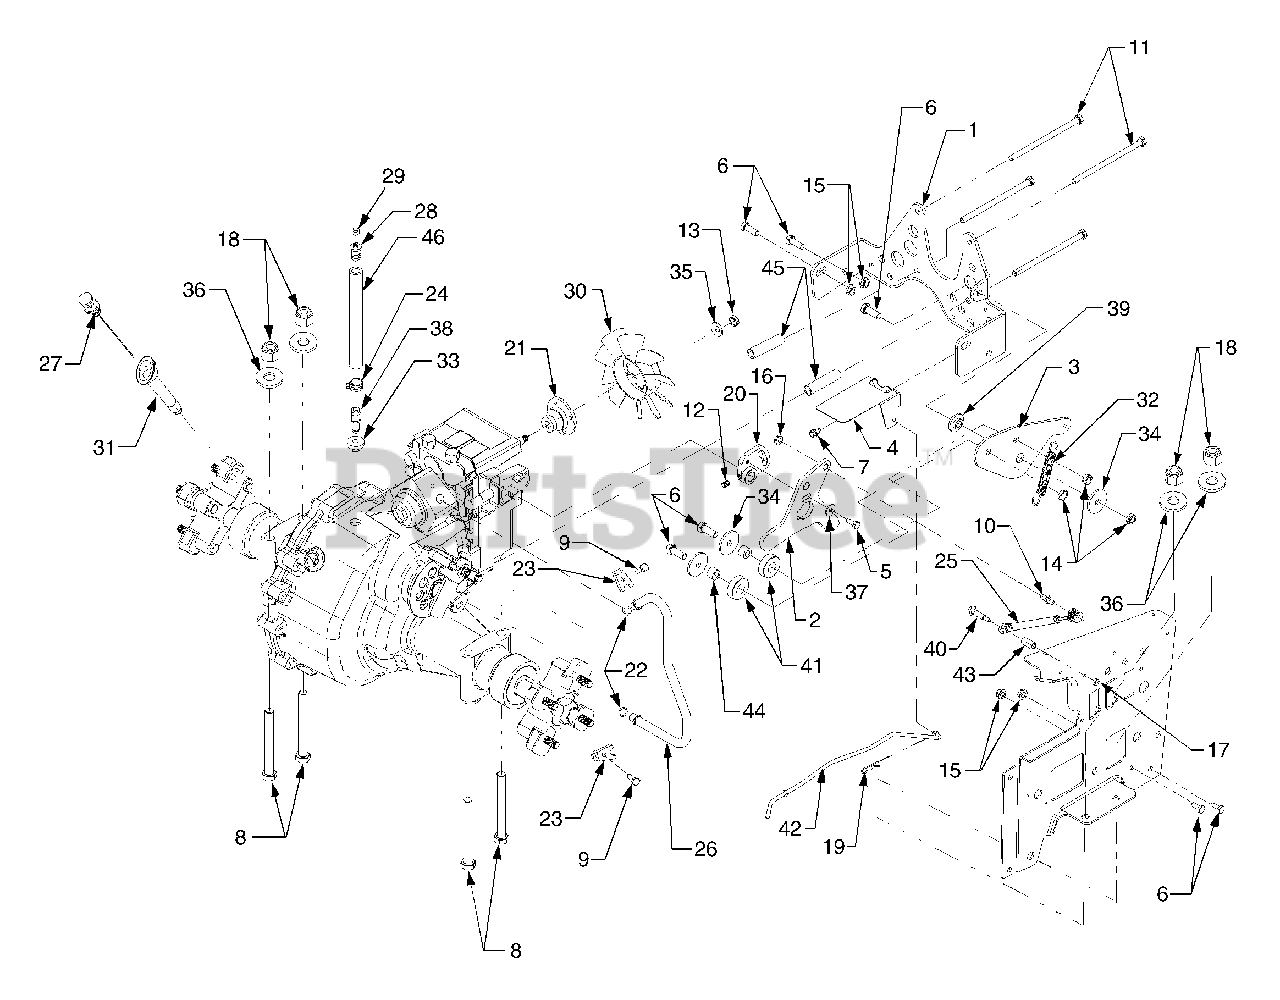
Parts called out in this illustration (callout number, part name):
1	Bracket, Torque
2	Plate, Hydro Neutral Return
3	Link, Neutral Return Bearing
5	Screw, Hex Cap, 1/4-20 x .625 GR5 Lock
6	Screw, Hex Cap, 3/8-16 x 1.0 GR5
7	Screw, Hex Wash. Hd. Tapp, 1/4-20 x .5
8	Screw, Hex Cap, 1/2-20 x 4.5 GR5
9	Screw, Hex Cap, 1/4-20 x .75 GR5
10	Ball Screw, 5/16-18 x .56
11	Screw, Hex Wash. Hd. Tapp, 5/16-18 x 5.5 GR5
12	Screw, Set, 5/16 x .5
13	Nut, Hex Top Lock Jam, 1/2-20
14	Nut, Hex Ctr. Lock Jam, 3/8-16
15	Nut, Hex Flange Lock, 3/8-16
16	Nut, Hex Flange Lock, 5/16-18
17	Nut, Hex, 1/4-20
18	Nut, Hex Insert Lock, 1/2-20
19	Pin, Internal Cotter
20	Arm, Hydro
21	Adapter, Pump
22	O-Ring, .426 ID x .566 OD x .070
23	Clamp, Tube
24	Clamp, Hose
25	Cylinder, Damper
26	Tube, Hydro Pickup
27	Dipstick, Transmission
28	Plastic Vent
30	Fan, Pump
31	Holder, Dipstick
32	Spring, Extension
34	Washer, Flat, .390 x 1.5 x .1
35	Washer, Bell, .5 x 1.0 x .05
36	Washer, Flat, .531 x 1.062 x .134
37	Washer, Flat, .26 x .72 x .06
38	Fitting, Tube
39	Spacer, Shoulder
40	Shoulder Bolt
41	Bearing, Ball
42	Rod, Pump Bypass
43	Spacer, .375 x .5 x 1.02
44	Spacer, .375 x .624 x .445
45	Spacer, Hydro, .3223 x .60 x 2.44
